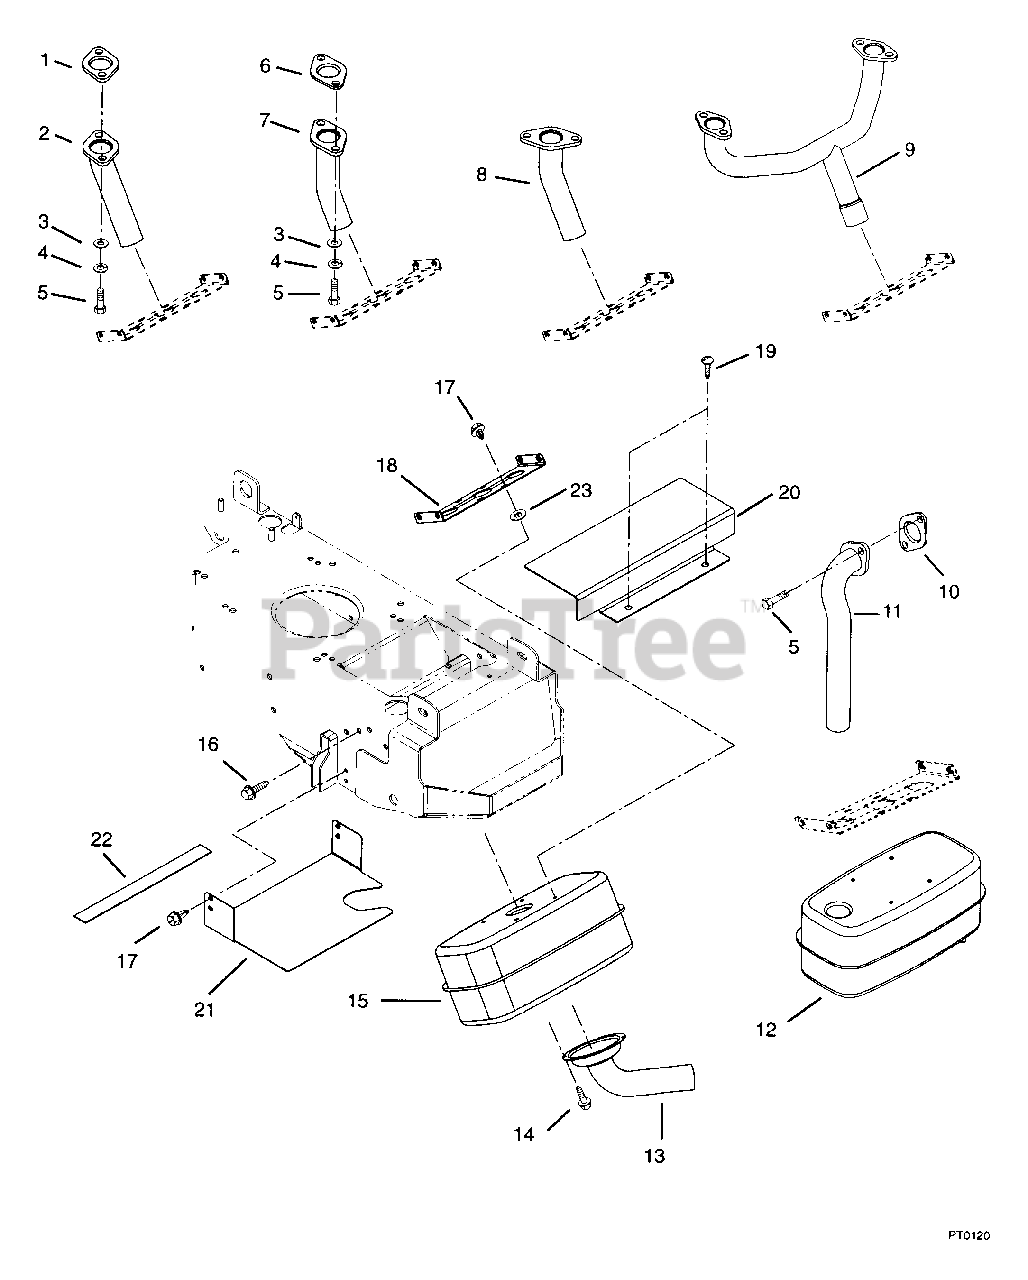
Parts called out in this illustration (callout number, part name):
1	GASKET- 12.5/13 TEC (#35-414)
2	TUBE - EXHAUST WELD. 13 HP
3	WSHR-FL-STL .323X.625X.062 PL
4	WSHR-LK .313X.078 PL MED
5	SCR-CAP .31-18X.75 S/HD
6	GASKET:15-16.5HP TEC (#35-438)
7	TUBE - EXHAUST WELD 15-16.5 HP
8	PIPE - EXHAUST
9	PIPE - EXHAUST TWIN B&S
10	GASKET B&S#272293
11	PIPE - EXHAUST
12	MUFFLER W/DEFLECTOR
13	DEFLECTOR - EXHAUST
14	SCR-TAP 8-32X.38 SL HWH PL 23
15	MUFFLER - EXHAUST
16	SCR-TAP .312-18X.50 HWH PL TR
17	SCR-TAP 12-24X.75 HWH PL TR
18	BRACKET - MUFFLER
19	SCR-TAP .312-18X.50 PL F
20	SHIELD - HEAT
21	SHIELD - HEAT
22	HEAT SHIELD- FABRIC 1X10.75
23	WSHR-FL-STL .390X.750X.125 PL
